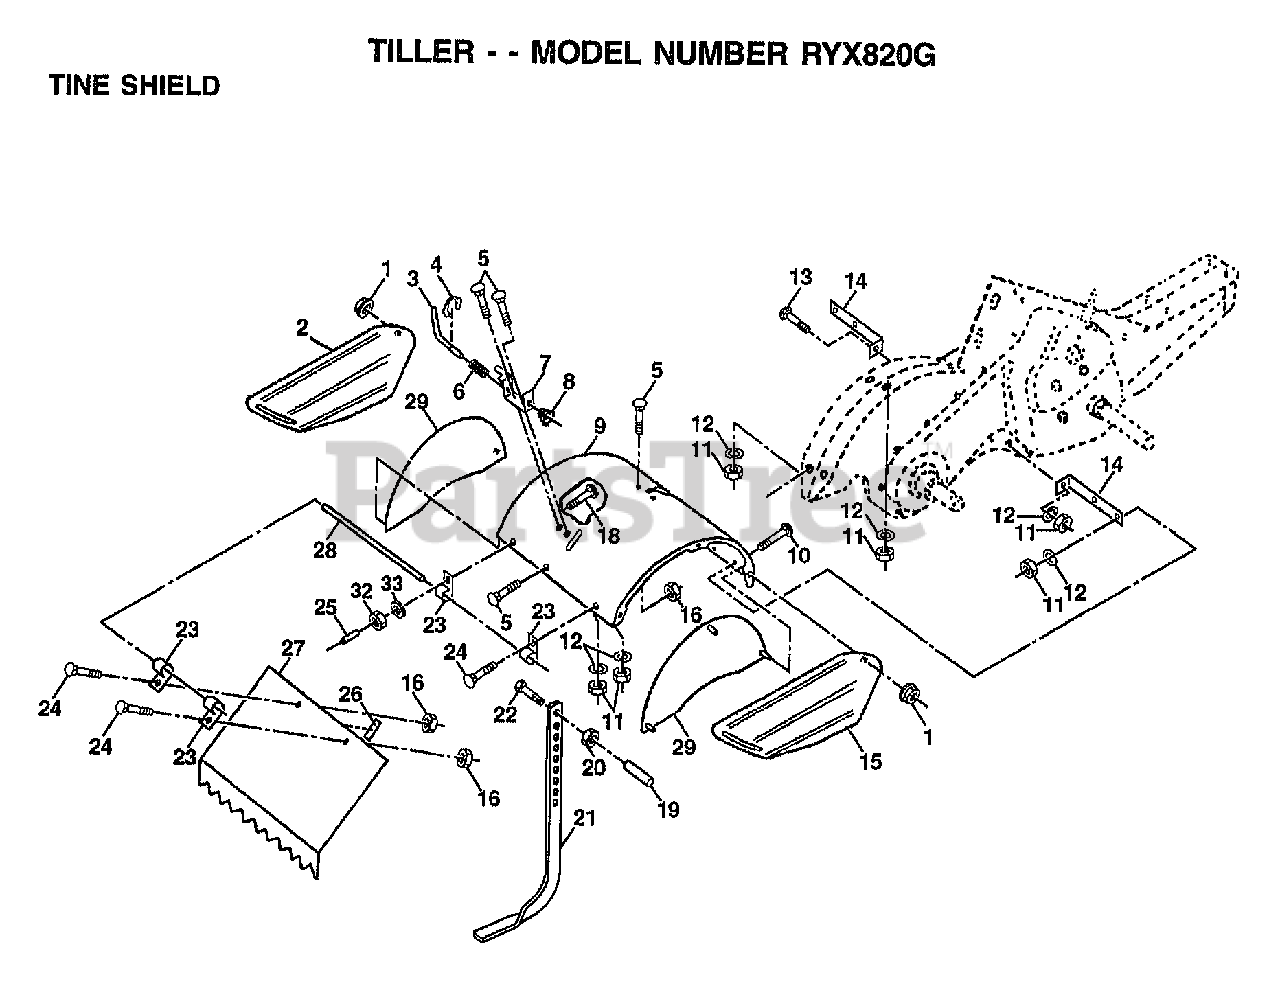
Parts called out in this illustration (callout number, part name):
1	"NUT HEX,LOCK,FLAN"
2	"SHIELD,SIDE,O.LH"
3	STAKE PIN TI
4	KLIP RING TI
5	BOLT
6	SPRING TI
7	LATCH BRACKET TI
8	SPRING CRT
9	"SHIELD, TINE"
10	BOLT
11	NUT.HEX.5/16-18
12	LOCKWASHER
13	BOLT
14	BRKT SHIELD TINE
15	SHIELD SIDE O.RH
16	NUT T
18	BOLT
19	GRIP CRT
20	NUT.HEX.3/8-16UNC
22	BOLT
23	HINGE CRT
24	BOLT
25	VINYL CAP TI
26	PAD IDLER TI
27	LEVELING SHIELD
28	PIN HINGE
29	"SHIELD, SIDE"
33	LOCKWASHER
